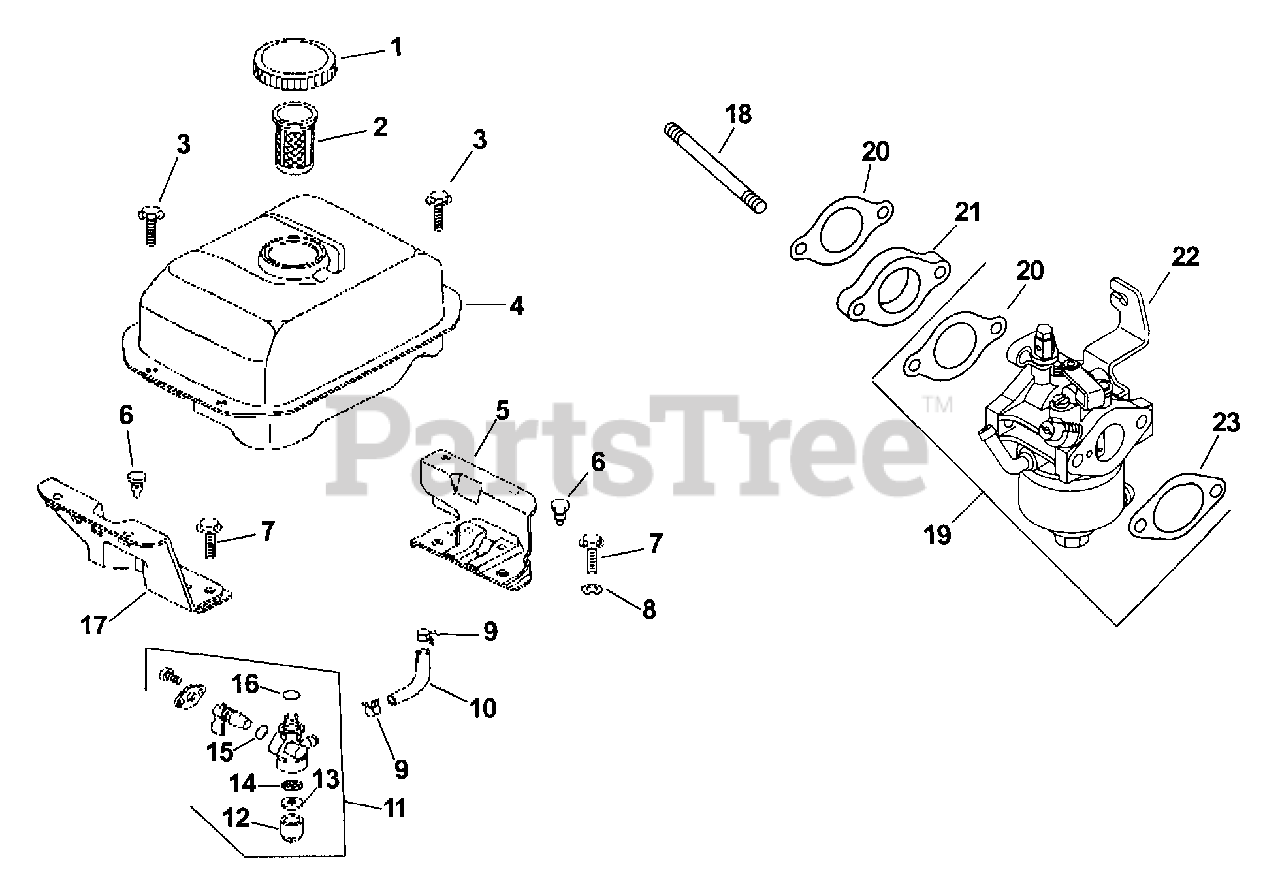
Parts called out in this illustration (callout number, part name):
1	CAP, FUEL TANK
4	TANK, FUEL
5	BRACKET, FUEL TANK
10	LINE, FUEL
11	VALVE, FUEL COCK ASSEMBLY
12	CUP, FILTER
14	FILTER SCREEN
17	BRACKET-FUEL TANK
18	STUD, CARBURETOR
19	KIT, CARBURETOR W/GASKET (CS6)
20	GASKET, INTAKE
21	MANIFOLD, INTAKE
22	KIT, CARBURETOR W/GASKET (CS6)
23	GASKET A/C
